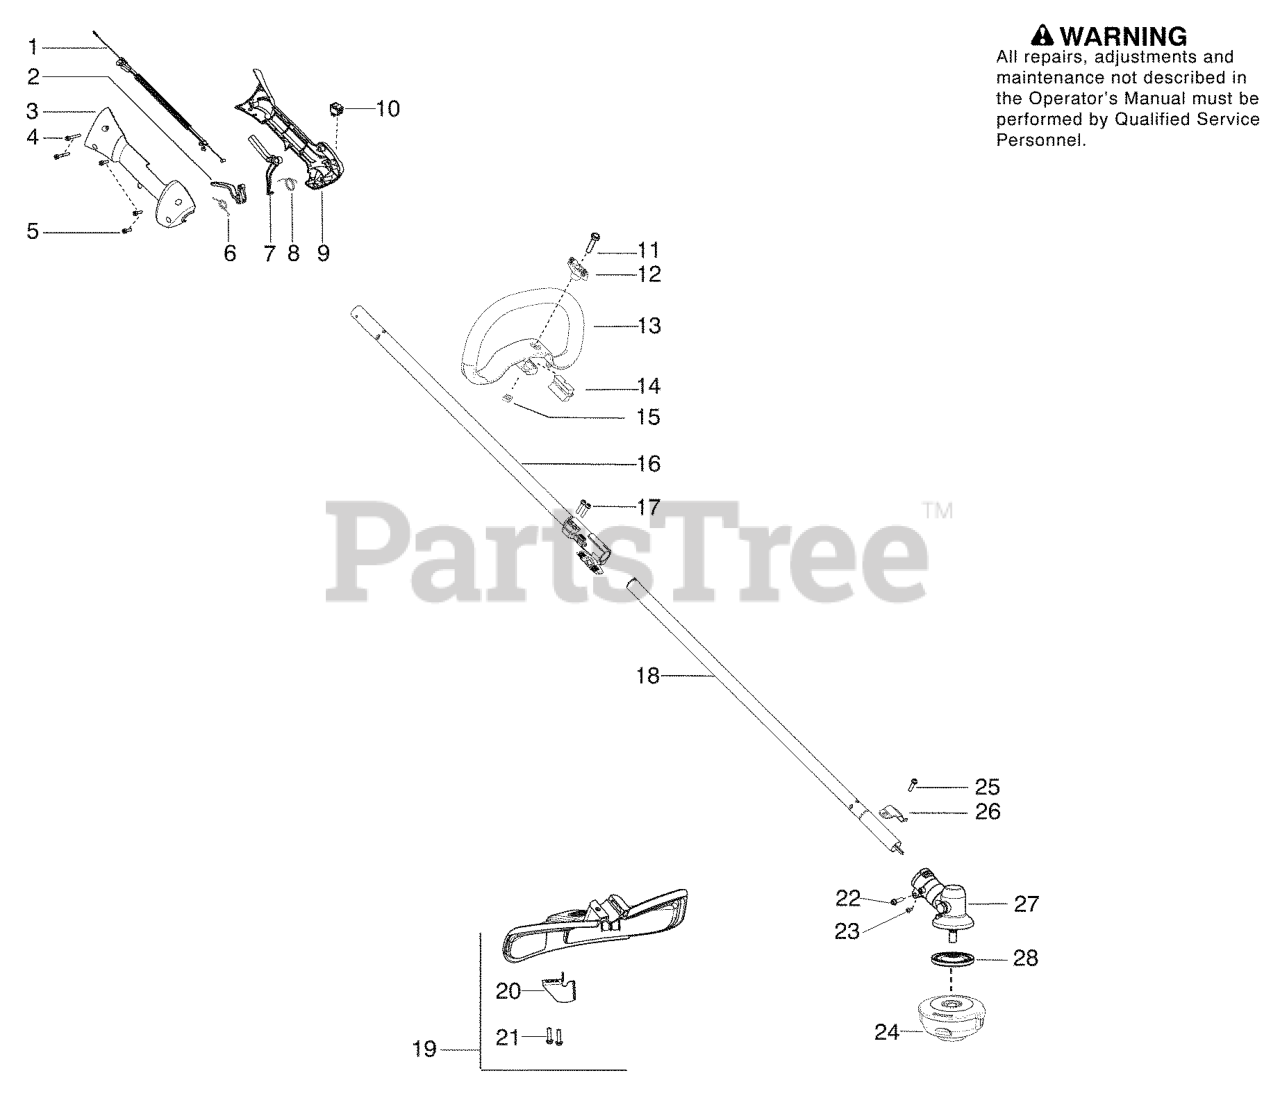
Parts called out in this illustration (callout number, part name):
1	ASSY-CABLE WIRE HARNESS
2	TRIGGER THROTTLE
3	HOUSING-THROTTLE RH
5	SCREW M4 X 1.75 PT 16MM
6	SPRING TRIGGER
7	THROTTLE LOCKOUT
8	SPRING LOCKOUT
9	HSG THROTTLE LH
10	KIT SWITCH
11	SCREW M6X55
13	ASSY LOOP HANDLE
14	SPACER PLASTIC
16	DRIVESHAFT
18	KIT LOWER SHAFT
19	KIT COBI SHIELD
20	Limiter-Line
22	SCREW - CARB. ADAPTOR
24	T25 TRIM HEAD 10MM LH
25	SCREW 1/4-20 X 7/8 (TAP
26	BRACKET SHIELD STRAIGHT SHAFT
27	ASSY GEARBOX
28	DRIVE DISC
